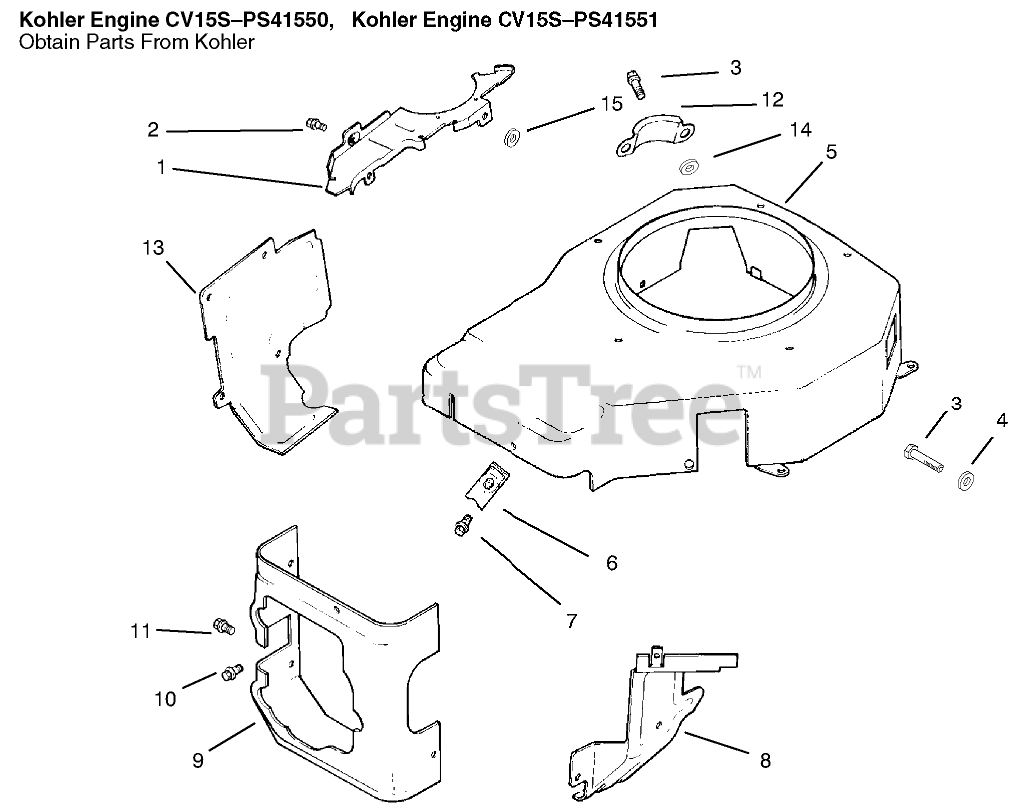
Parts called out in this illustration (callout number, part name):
1	Plate-Blower Housing
2	Screw
3	Screw
4	Washer
5	Housing-Blower
6	Clip
8	Baffle-Carburetor
9	Baffle-Cyl. Head
10	Screw
11	Screw
12	Cover-Pinion
13	Baffle-Cylinder
14	Washer
15	Washer
